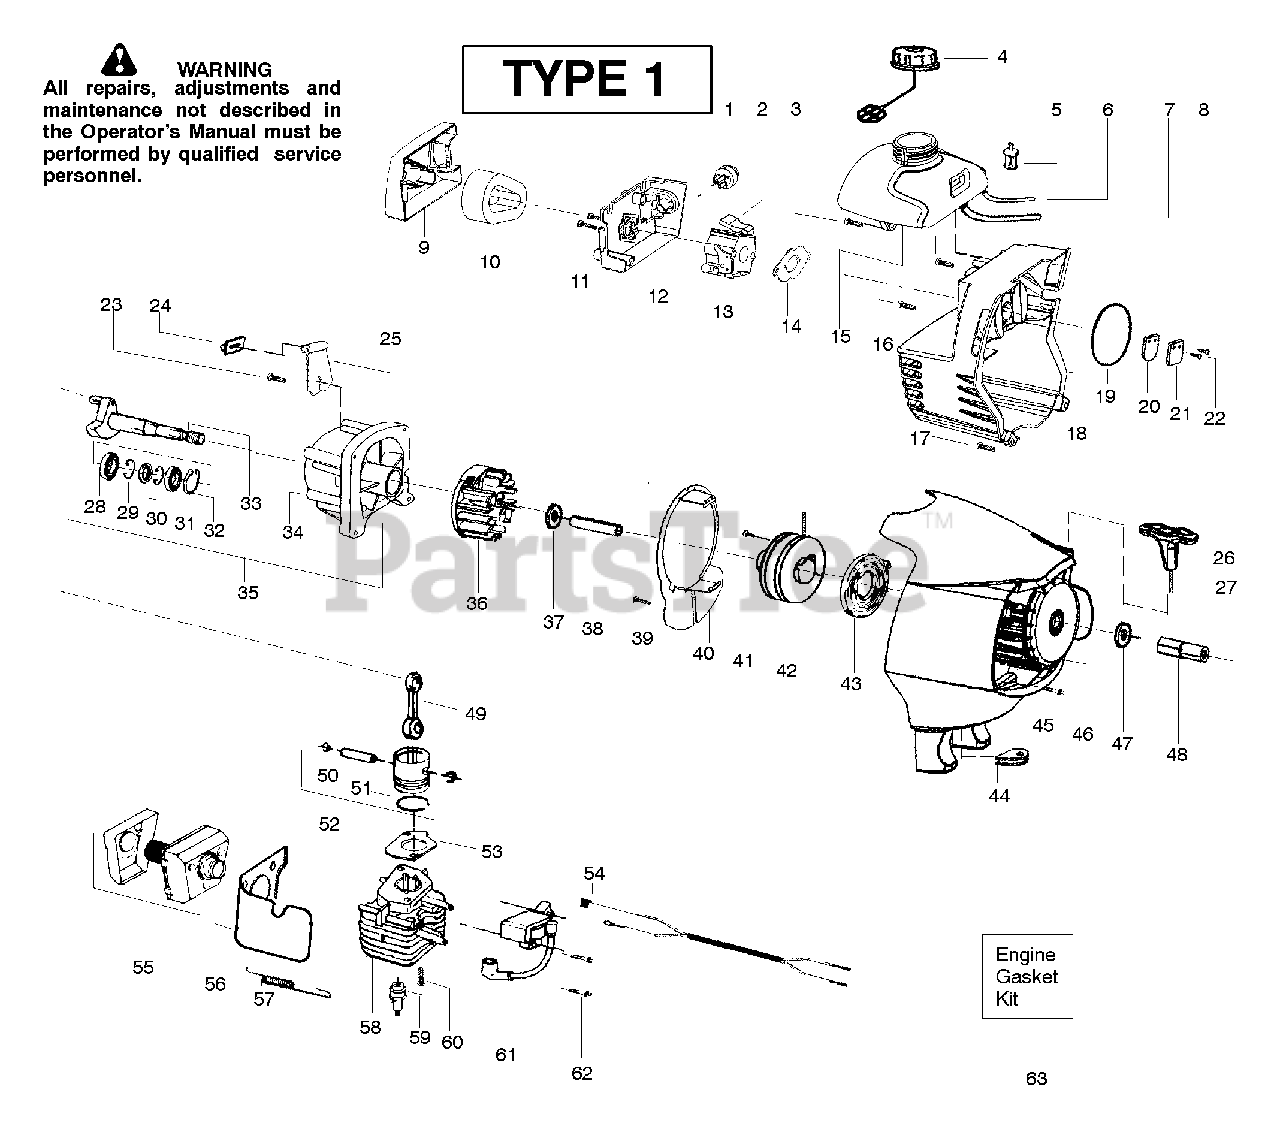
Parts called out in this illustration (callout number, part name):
1	Bulb-Purge
2	Kit-Choke Lever
3	Screw-tank
4	Cap-Fuel w/ret.
5	Assy-Fuel pickup
6	Kit-Fuel line
7	Kit-Fuel/Purge line
9	Cover-Air box
10	Filter-Air
11	Screw-Carb.
13	Assy-Carb(WT628)
14	Gasket-Carb. (kit)
15	Assy-Fuel Tank
16	Screw-Crankcase
17	Screw-Shroud
19	O-ring-Shroud (kit)
20	Valve-Reed
21	Stop-Reed
22	Screw-Reed stop
23	Screw-Retainer
24	Isolator-Tank
25	Ret.-Tank
26	Handle-Starter
27	Kit-Rope
28	Bearing-Inner
29	Retainer
31	Bearing-Outer
32	Ret.-Crankshaft
33	Assy-Crankshaft
34	Assy-Crankcase
35	Assy-C'case/C'shaft
36	Kit-Flywheel Assy.
39	Screw-Baffle
40	Plate-Baffle
41	Screw-Rope
42	Kit-Pulley
43	Spring-Starter
45	Screw-F/hsg.
46	Assy.-Fan Housing
48	Coupling-Drive
49	Assy-Conn. Rod
50	Ret.-Piston pin
51	Ring-Piston
52	Kit-Piston
53	Gasket-Cylinder (kit)
54	Assy-Leadwire
55	Kit-Muffler
57	Spring-Muffler
58	Kit-Cylinder
59	Plug-Spark (RCJ-6Y)
60	Bolt-Cyl. 1/4-20"
61	Module-Ignition
62	Screw-Module
63	Kit-Gasket
